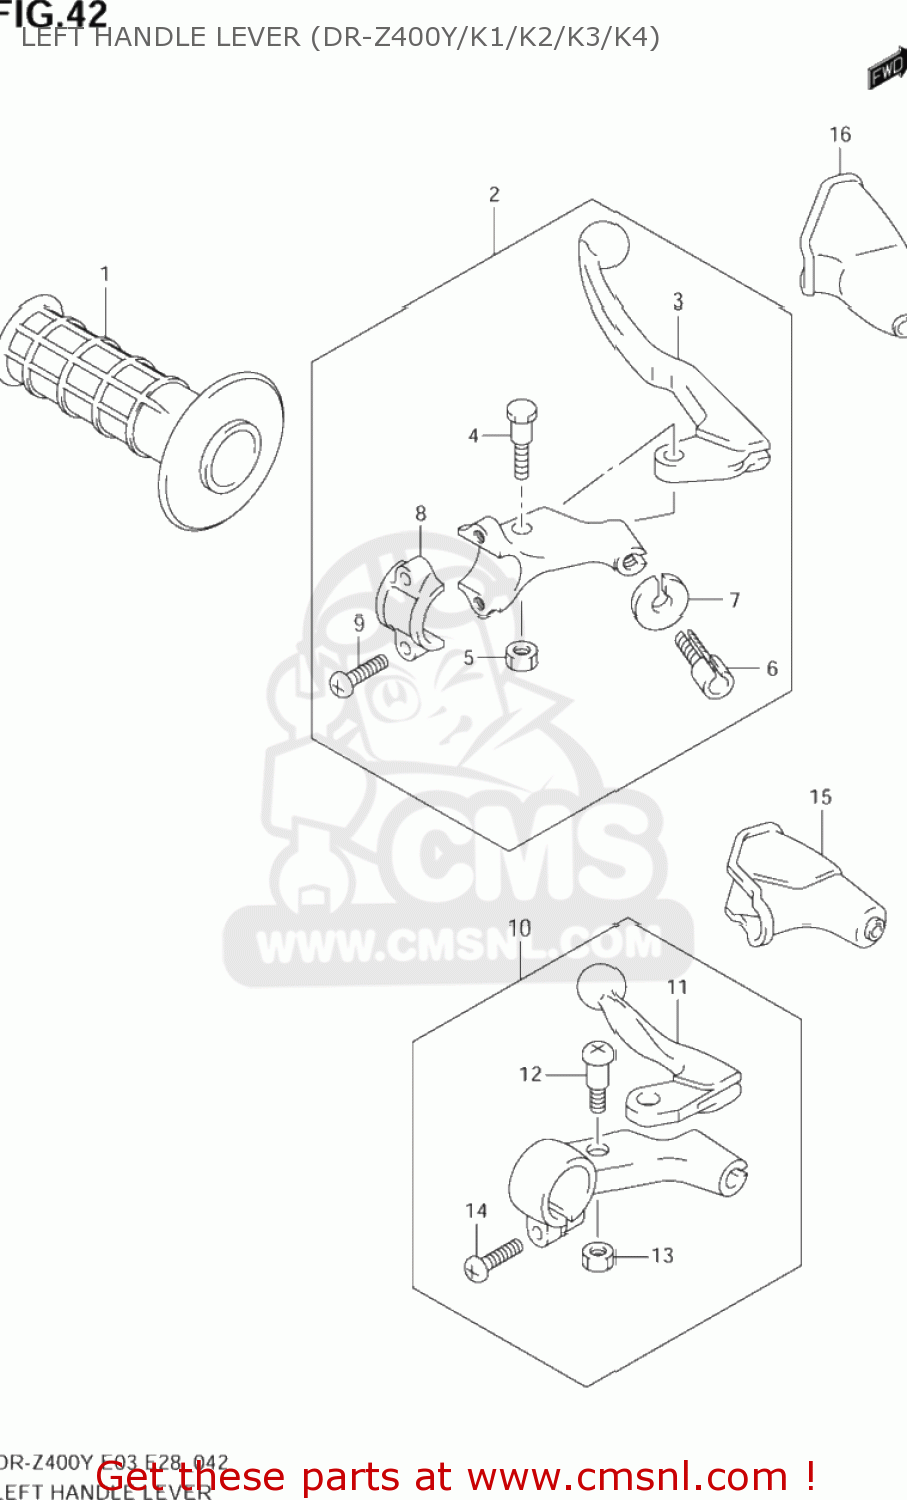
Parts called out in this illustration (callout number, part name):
1	GRIP,L
2	LEVER ASSY,CLUTCH
3	LEVER,CLUTCH
4	BOLT,LEVER PIVOT
5	NUT 6MM
6	ADJUSTER,CABLE
7	NUT,CABLE ADJUSTER
8	BRACKET,CLUTCH LEVER HOLDER
9	SCREW(5X14)
10	LEVER ASSEMBLY,DECOMPRESSION
11	LEVER,DECOMP
12	BOLT,LEVER PIVOT
13	NUT
14	SCREW, 6X20
15	COVER,DECOMP LEVER DUST
16	COVER,CLUTCH LEVER
